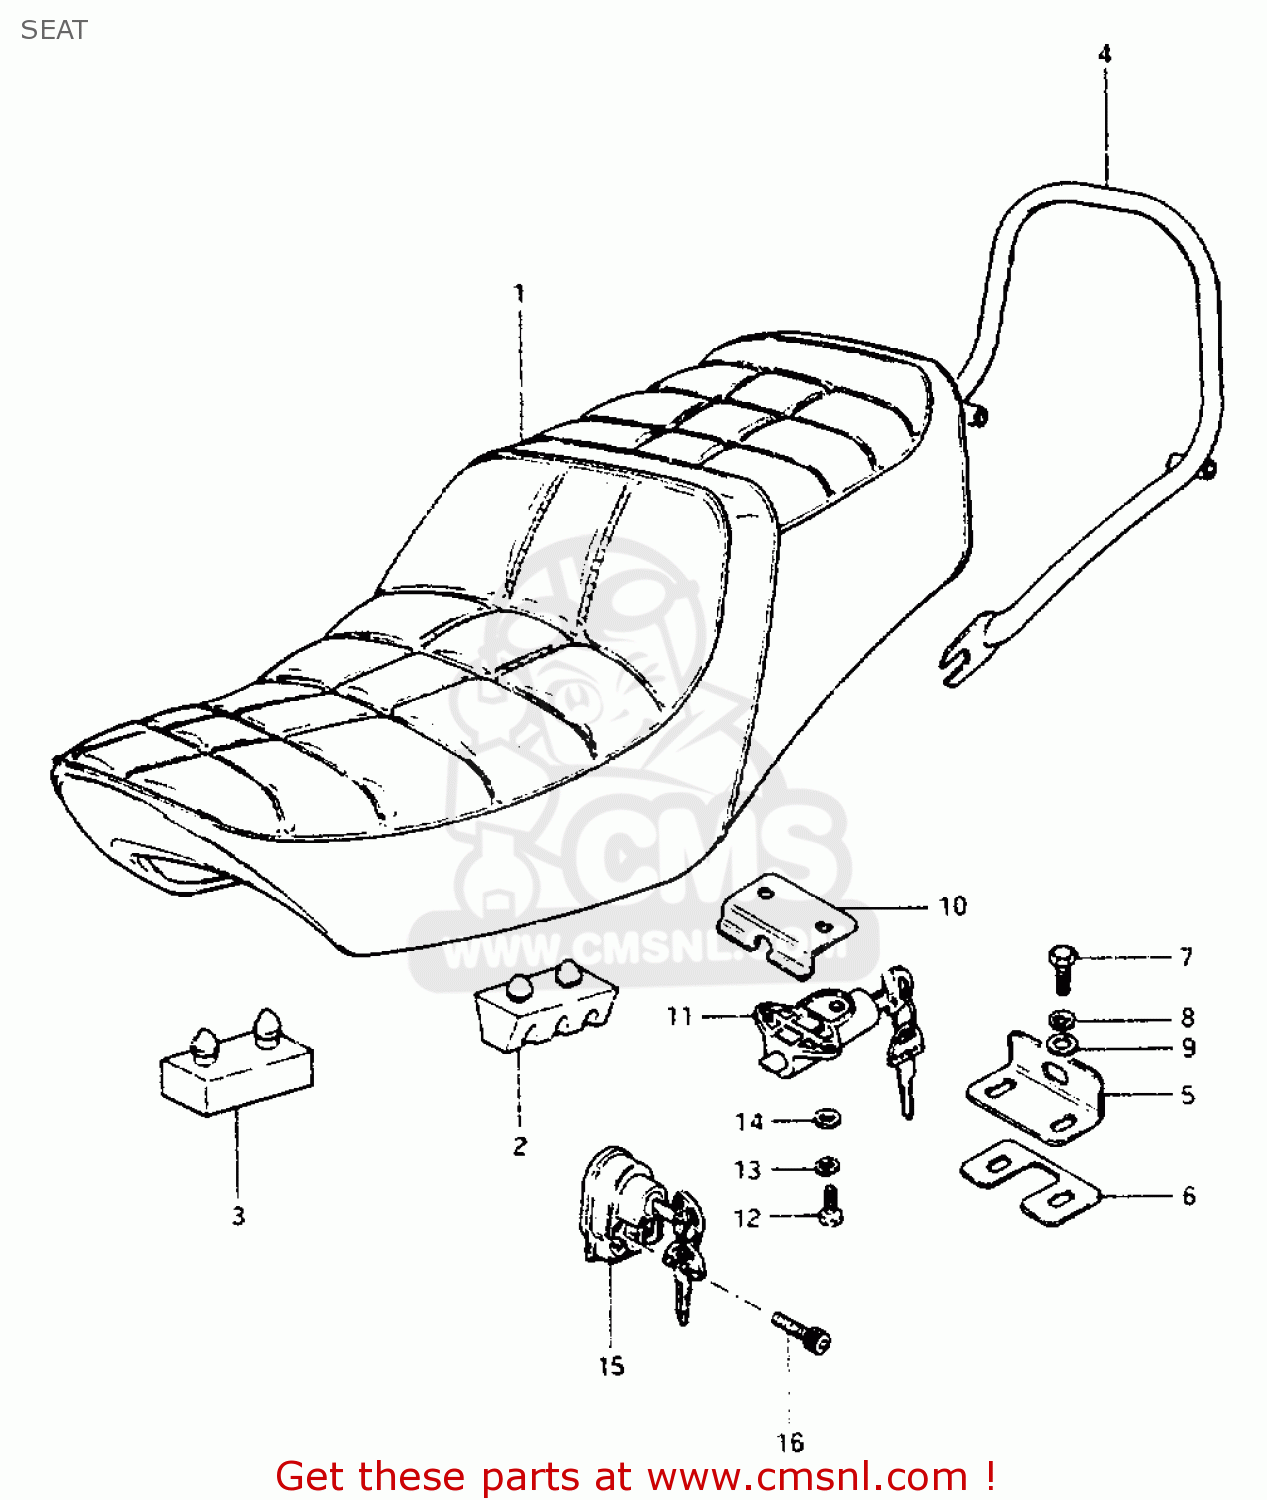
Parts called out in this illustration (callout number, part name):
1	SEAT ASSY (BLACK)
2	CUSHION,SUPPORT(50X25X32)
3	CUSHION
4	HANDLE,PILLION RIDER
5	STRIKER, SEAT LOCK
6	SHIM,SEAT LOCK STRIKER
7	BOLT, UPPER
8	LOCK WASHER
9	WASHER
10	GUIDE, PLATE
11	LOCK ASSEMBLY,SEAT
12	BOLT
13	LOCK WASHER
14	WASHER
15	LOCK ASSY,HELMET
16	BOLT 5X25
